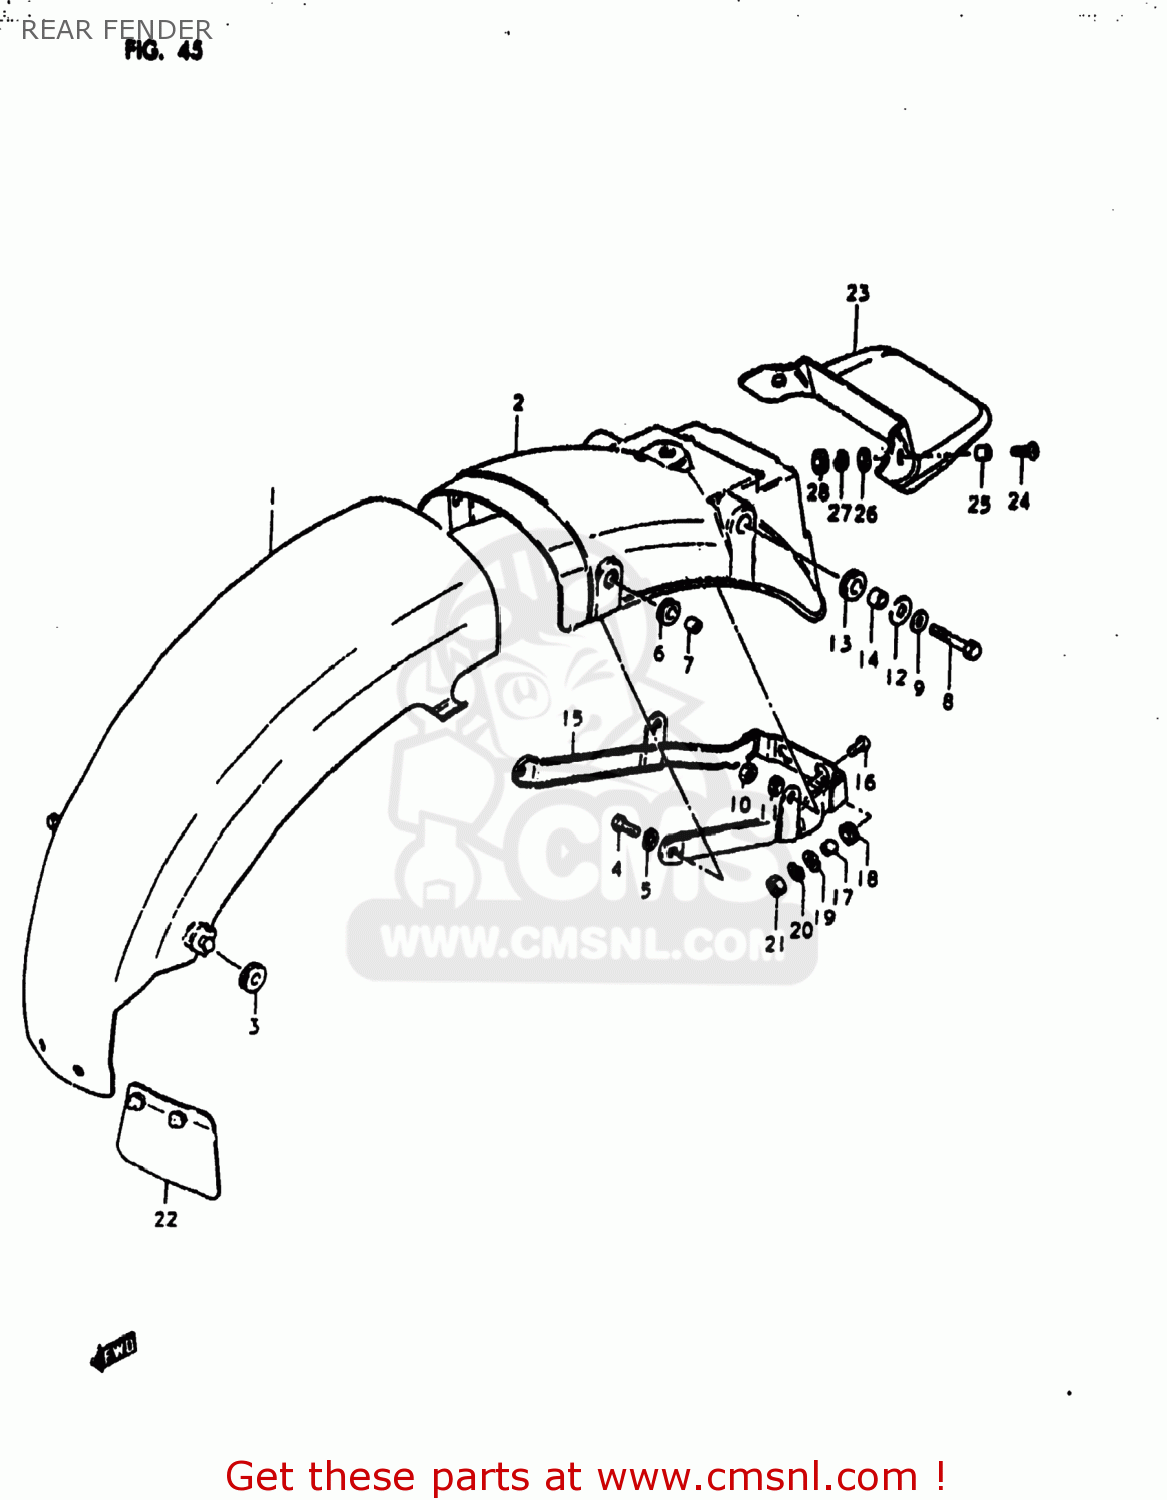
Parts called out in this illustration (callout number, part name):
1	FENDER,REAR
2	BODY,RR FENDER RR
3	CUSHION
4	BOLT
5	LOCK WASHER
6	CUSHION
7	SPACER(6.1X9X7.5)
8	BOLT
9	WASHER
10	NUT
11	LOCK WASHER
12	WASHER(8.5X26X1.2)
13	CUSHION
14	SPACER (8.2X12X7.5)
15	REINFORCEMENT,REAR FENDER
16	SCREW
17	SPACER (6.1X9X9)
18	CUSHION
19	WASHER(6,5X22X1.6)
20	LOCK WASHER
21	NUT
22	GUIDE,RR FENDER MUD
23	EXTENSION,REAR FENDER
24	SCREW (6X15)
25	SPACER(6.2X8.3X5.7)
26	WASHER(6.5X18X1)
27	LOCK WASHER
28	NUT
